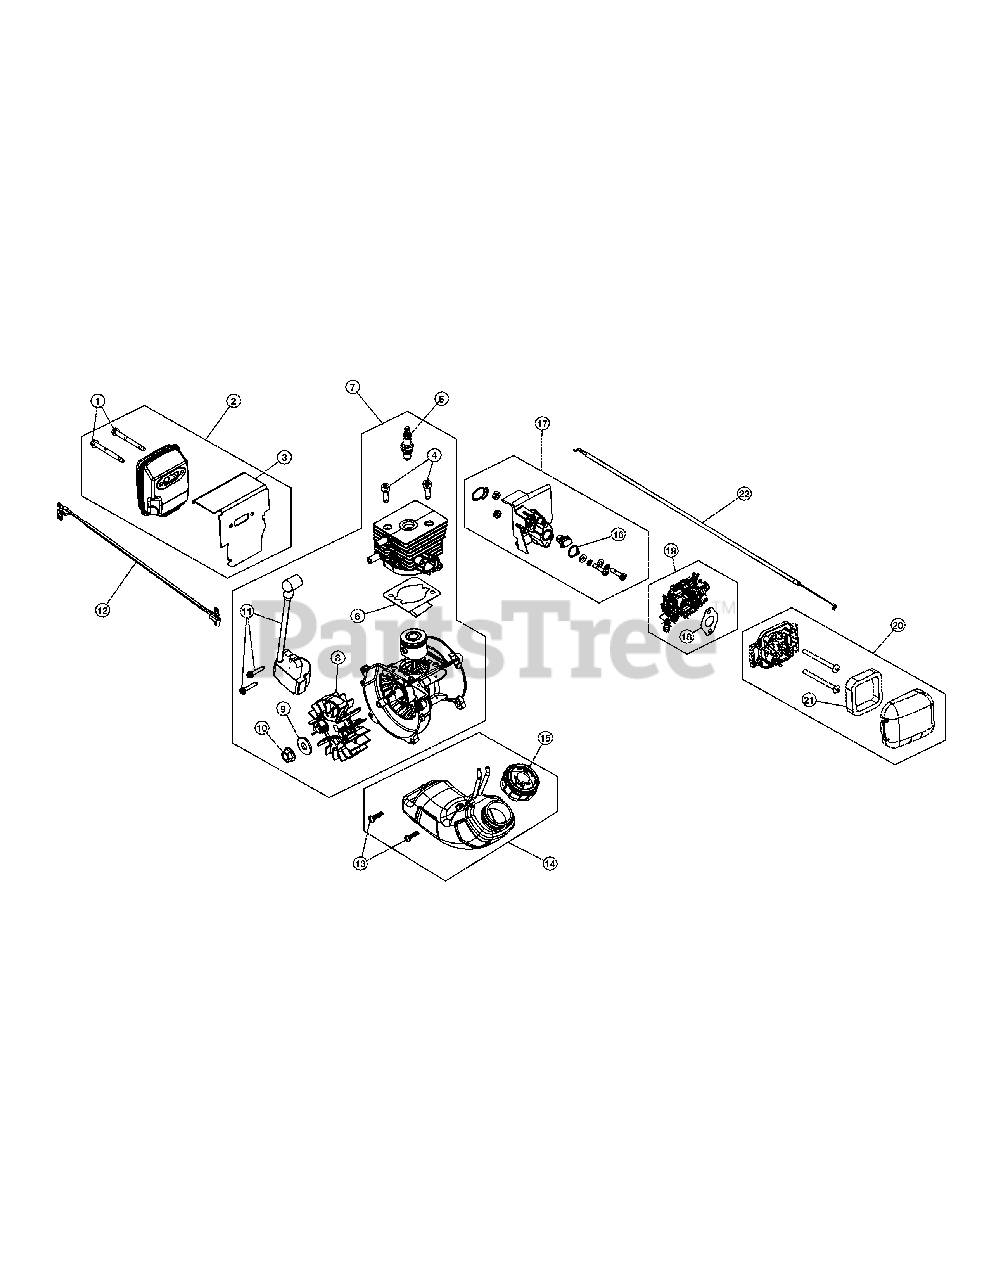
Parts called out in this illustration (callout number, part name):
1	Muffler Screws
2	Muffler Assembly
3	Muffler Gasket
5	Spark Plug
6	Cylinder Gasket
7	Shortblock Assembly
8	Flywheel Assembly
9	Washer
11	Module Assembly
12	Lead Wire
14	Fuel Tank Assembly
15	Fuel Cap
16	Insulator Gasket
17	Insulator Assembly
18	Carburetor Gasket
19	Carburetor Assembly
20	Aircleaner Assembly
21	Air Filter
22	Throttle Cable
